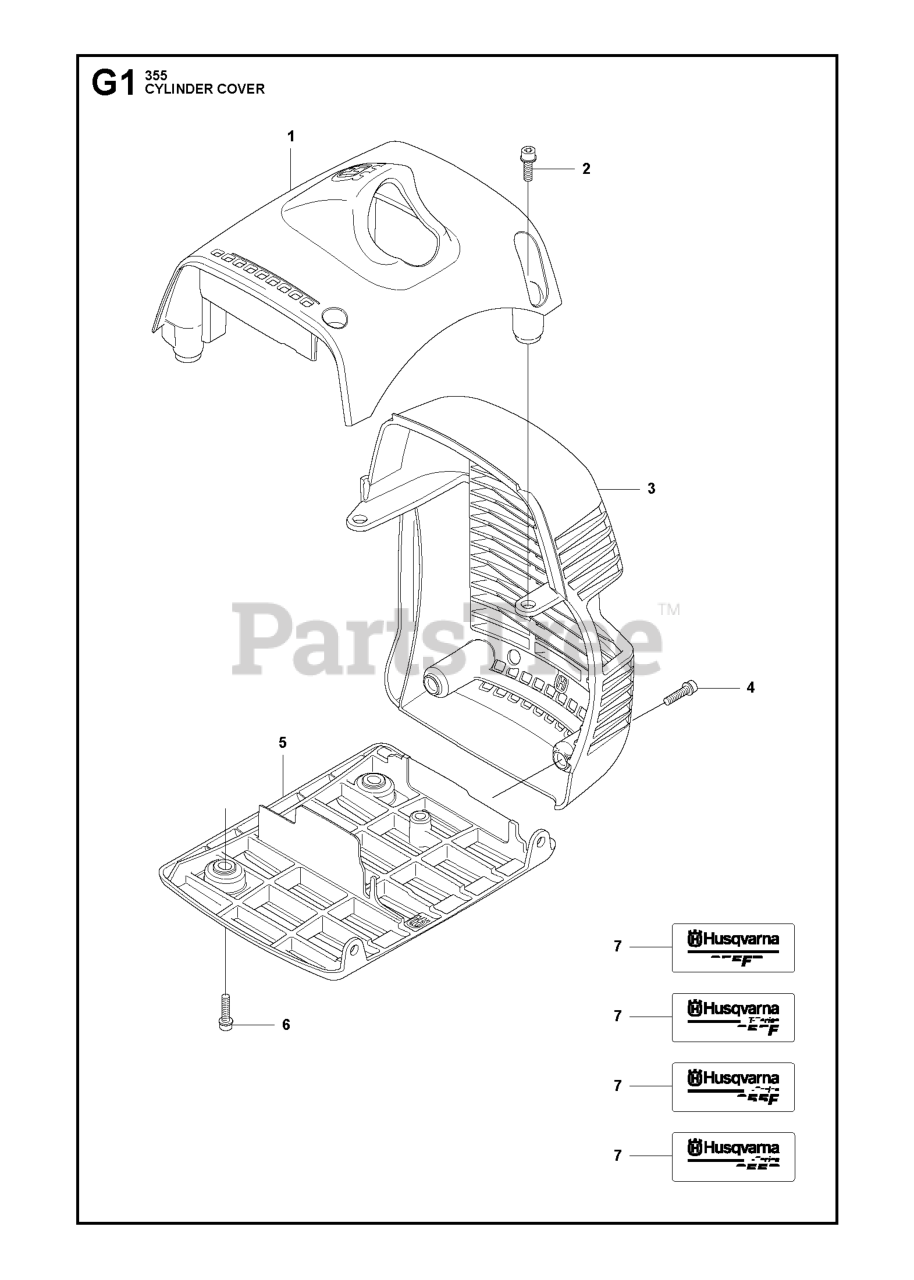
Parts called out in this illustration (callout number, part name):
1	CYLINDER COVER
3	HEAT PROTECTOR
5	PROTECTIVE COVER ASSY HUSQ
7	LABEL
